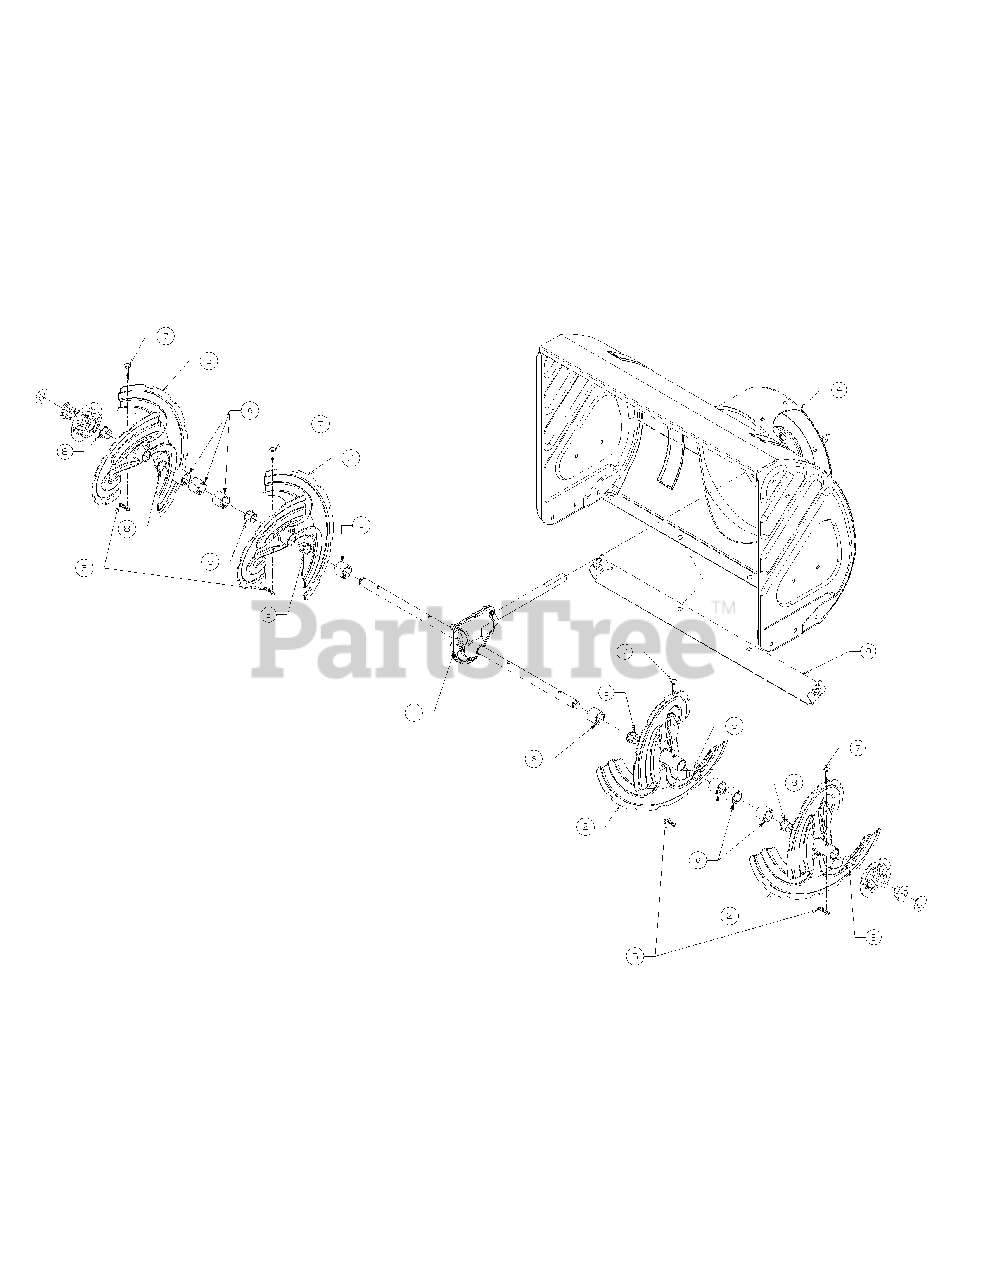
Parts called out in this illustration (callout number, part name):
1	Gearbox Asm-Auger 28"
2	Auger Assembly-LH
3	Auger Assembly-RH
4	Housing Assy-Auger
5	Pin-Cotter
6	Spacer 1.25Od X
7	Pin-Shear .25
8	Bearing-Flange
9	Plate-Shave 28"
